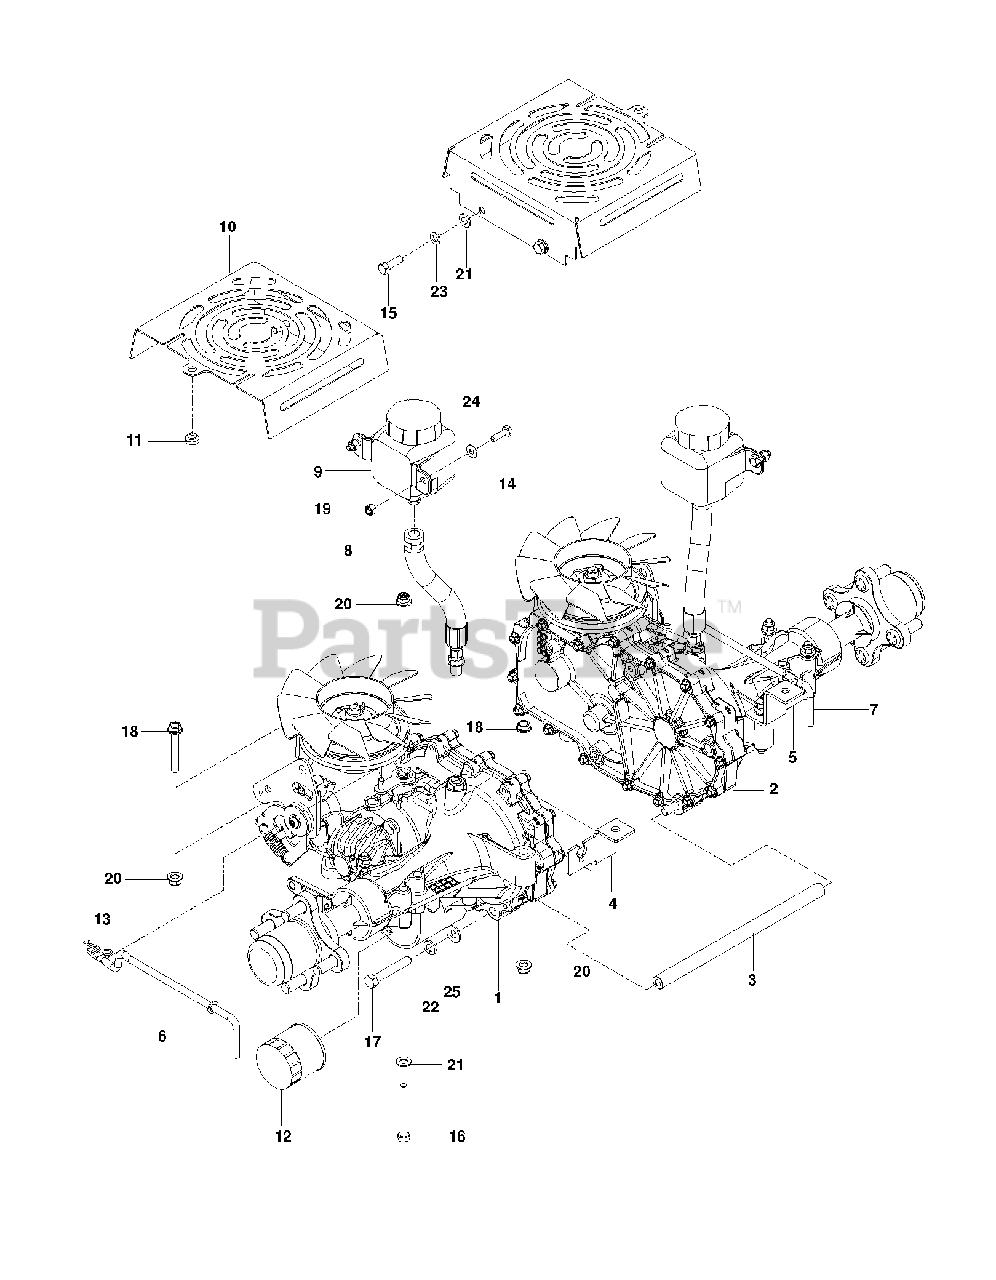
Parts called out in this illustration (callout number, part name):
1	HG_TRANS, ZT-3400, LT
2	HG_TRANS, ZT-3400, RT
3	TUBE, SPACER, 3400
4	BRACKET.TRANS.LT.BLACK
5	BRACKET, TRANS, RT BLACK
6	LINKAGE, LEFT BYPASS
7	LINKAGE, RIGHT BYPASS
8	HOSE ASSY, EXPANSION
9	TANK.EXPANSION.350ML 71328
10	SHIELD, FAN, BLK
11	GROMMET, BUMPER
12	HG_FILTER, ZT4800 52114
13	HAIRPIN #2
14	HCS 1/4-20X7/8 GR5
15	HCS 5/16C X 1
16	HCS 5/16C X 2-3/4
17	HCS 3/8-16X2-1/4 LOC PATCH GR8
18	HHFS 5/16-18 X 2.25 GD 5
19	RP_NUT 1/4-20 NYLOC
20	5/16-18 NYLOC FLANGE NUT
21	FLAT WASHER 5/16 SAE
22	SLW 3/8 STD
23	WASHER 5/16 LOCK
24	WASHER 1/4 SAE
25	WASHER 3/8 SAE FLAT
